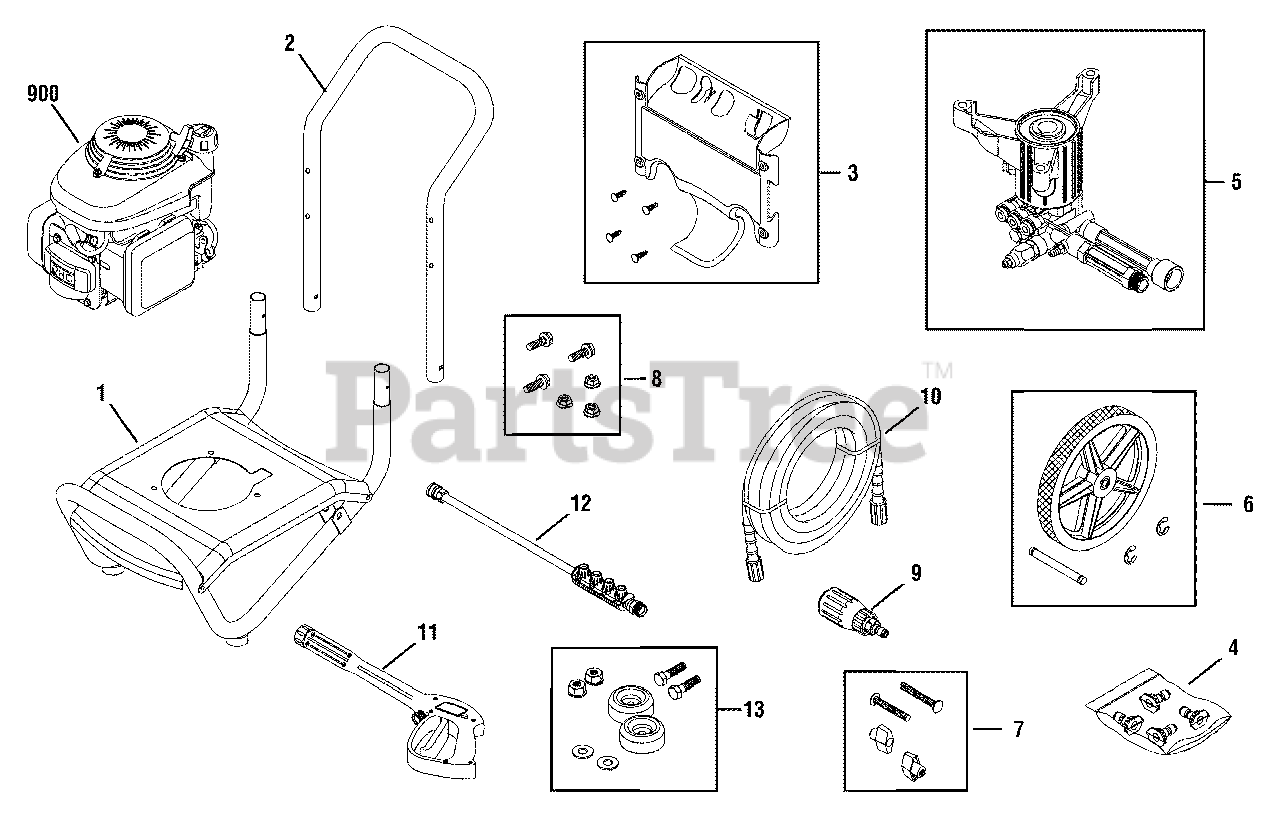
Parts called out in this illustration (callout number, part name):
3	KIT, Billboard w/Decal & Clips
4	KIT, Nozzles
5	PUMP
7	KIT, Fastening Handle
8	KIT, Pump/Engine Mounting Hardware
9	NOZZLE, Turbo Head
10	HOSE, 25'
11	GUN
12	EXTENSION, w/Nozzle Holder
13	KIT, Vibration Mount
900	* ENGINE
